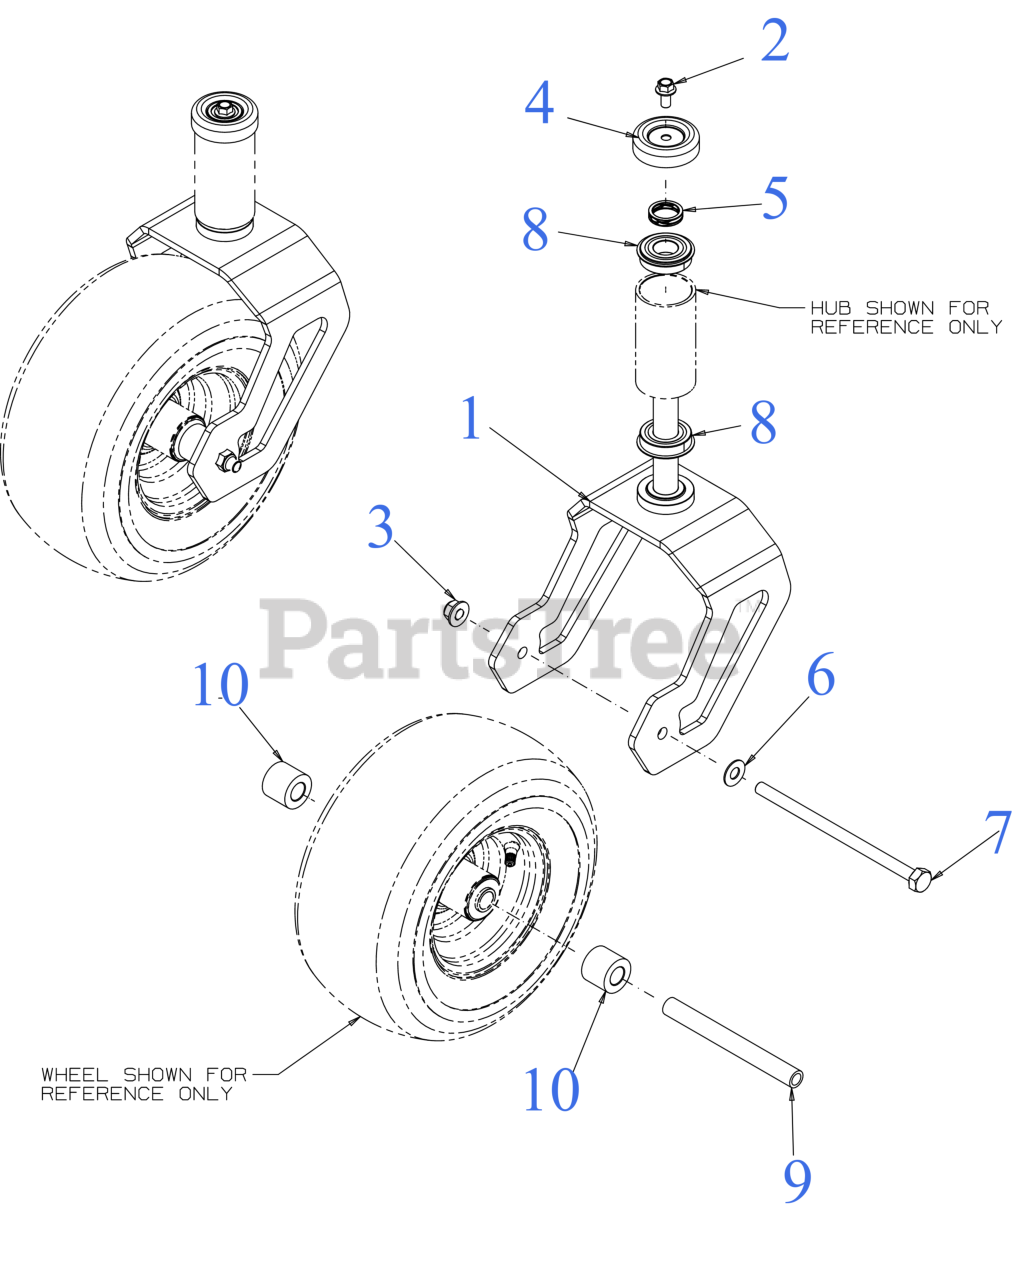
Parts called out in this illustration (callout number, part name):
1	CASTER WHEEL YOKE
2	BOLT - 3/8-16:.75:GR5:PATCH LOCK
4	AXLE CAP
5	WAVE WASHER
6	FLAT WASHER
7	SCREW-1/2-13X8.5 GR5 FLG RZF-SX
8	BALL BEARING 25X52X15
9	CASTER AXLE SPACER
10	CASTER WHEEL SPACER
